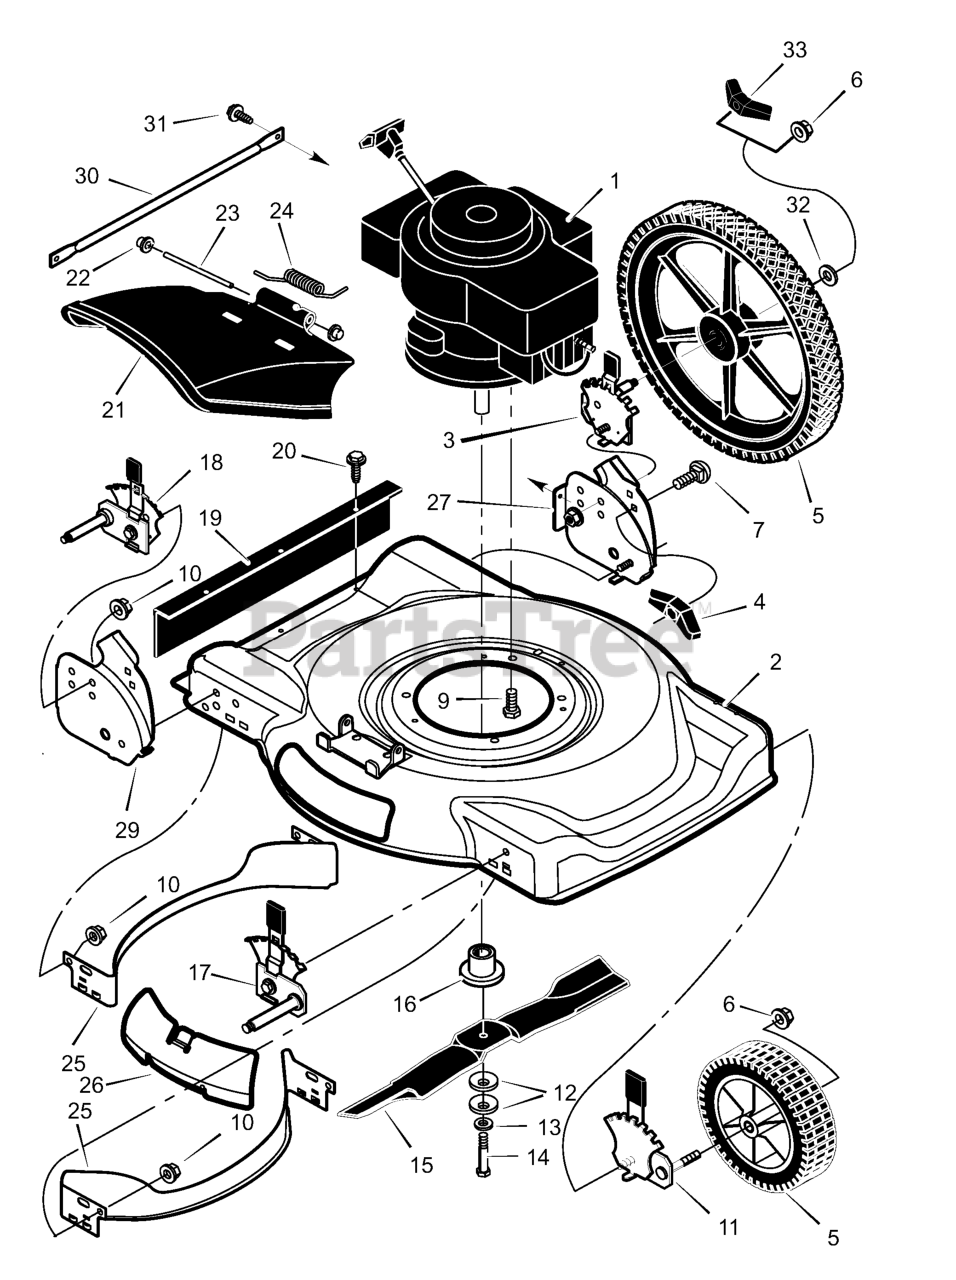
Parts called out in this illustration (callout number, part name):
1	Engine *
2	Housing
3	Height Adjuster, Left Rear
5	Wheel and Tire, Front
6	Locknut, Flange
7	Bolt, Carriage
9	Bolt, Engine
10	Nut
11	Height Adjuster, Left Front
12	Washer, Belleville
14	Bolt, Hex
15	Blade, Mulcher
16	Adapter, Blade
17	Height Adjuster, Right Front
18	Height Adjuster, Right Rear
19	Guard, Rear
21	Deflector, Chute
22	Push-On Cap
23	Pin, Pivot
26	Plate, Mulcher
27	Bracket, Left Handle
29	Bracket, Right Handle
33	Knob, Axle
